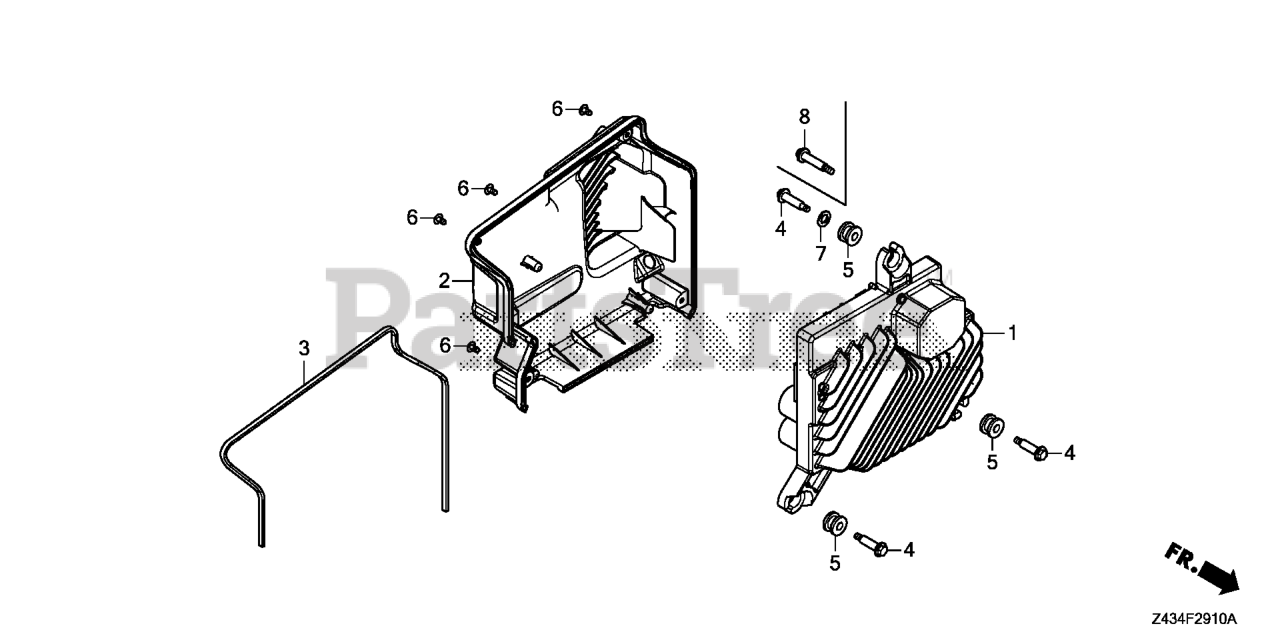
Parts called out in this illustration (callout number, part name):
1	INVERTER UNIT
2	COVER, INVERTER *NH1* (BLACK)
3	SEAL, INVERTER COVER
4	BOLT, CONTROL CASE
5	RUBBER, INVERTER UNIT
6	SCREW, TAPPING (5X12)
7	WASHER, PLAIN (10MM)
